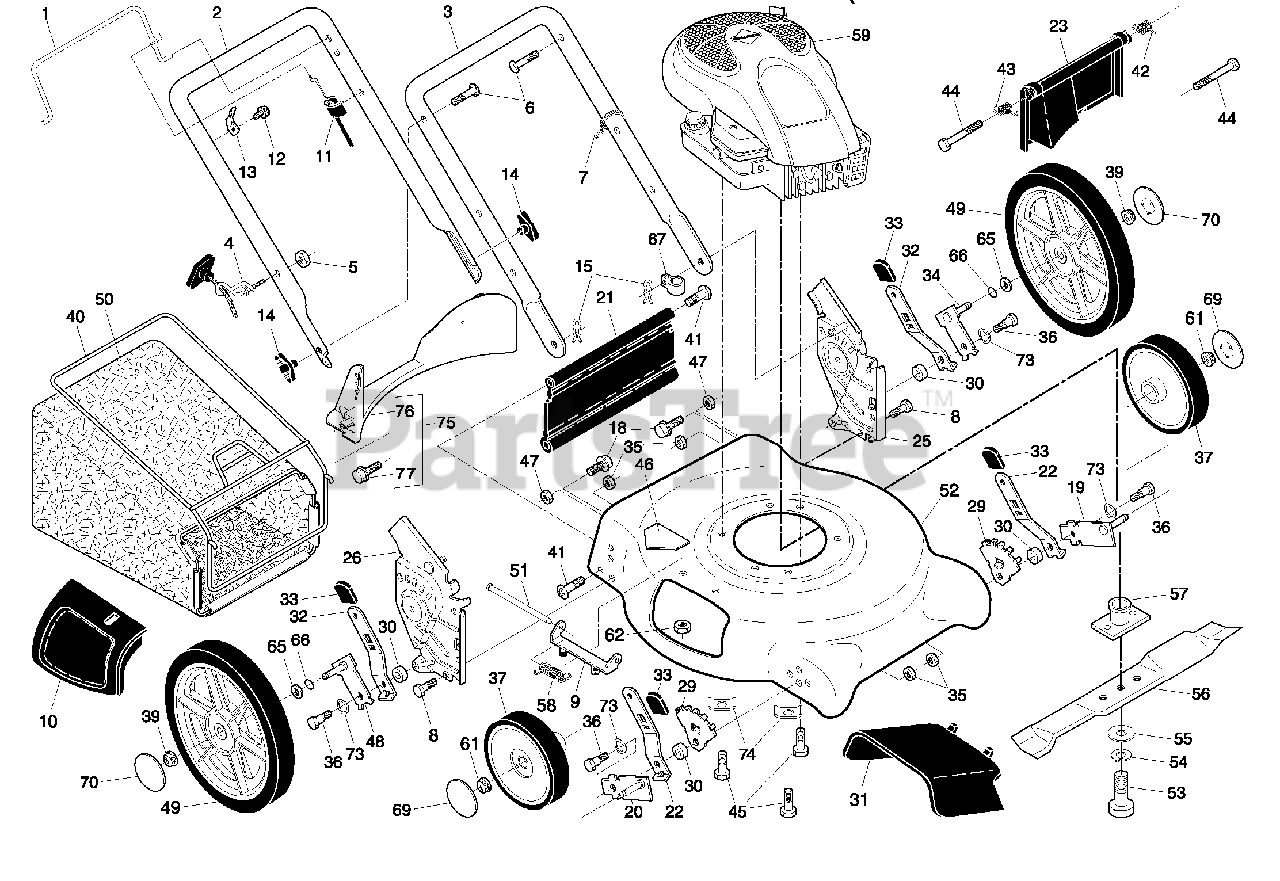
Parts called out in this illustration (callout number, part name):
1	Control Bar
2	Upper Handle
3	Lower Handle
4	Rope Guide
5	Locknut, Hex 1/4-20
6	Handle Bolt
7	Wire Tie
8	Hex Bolt 5/16-18 x 3/4
9	Mounting Bracket, Mulcher Door
10	Mulcher Door
11	Engine Zone Control Cable
12	Hex Washer Head Screw #10-24 x 1/2
13	Up-Stop Bracket
14	Handle Knob
15	Hairpin Cotter
18	Screw
19	Axle Arm Assembly, Front, LH
20	Axle Arm Assembly, Front, RH
21	Rear Skirt
22	Selector Spring, Front
23	Rear Door Assembly
24	Locknut, Hex 5/16-18
25	Handle Bracket, LH
26	Handle Bracket, RH
28	Wheel Adjusting Bracket
30	Spacer
31	Deflector, Discharge
32	Selector Spring, Rear
33	Selector Knob
34	Axle Arm Assembly, Rear, LH
35	Locknut, Hex 5/16-18
36	Shoulder Bolt 5/16-18
37	Wheel & Tire Assembly, Front, 8"
38	Shoulder Bolt
39	Flanged Locknut
40	Frame, Grassbag
41	Hinge Screw
42	Spring, Rear Door, LH
43	Spring, Rear Door, RH
44	Bolt, Rear Door
45	Screw, Hex Head Thread Rolling Screw 3/8-16 x 1
46	Danger Decal
47	Nut, Hex
48	Axle Arm Assembly, Rear, RH
49	Wheel & Tire Assembly, Rear, 12"
51	Rod, Hinge
52	Kit, Lawn Mower Housing
53	Hex Head Screw, Grade 8, 3/8-24 x 1-3/8
54	Helical Lockwasher
55	Hardened Washer
56	21" Blade
57	Blade Adapter
58	Spring, Hinge Rod
61	Flanged Locknut
62	Nut, Hex
65	Washer, Flat 3/8
66	O-Ring
67	Clip, Cable
69	Hubcap, Front Wheel
70	Hubcap, Rear Wheel
73	Washer, Curved, Cylindrical
74	Washer, Special, Engine
75	Kit, Rear Baffle
76	Baffle, Rear
77	Screw, Rear Baffle
77	Operator's Manual, English
77	Operator's Manual, French
77	Repair Parts Manual
